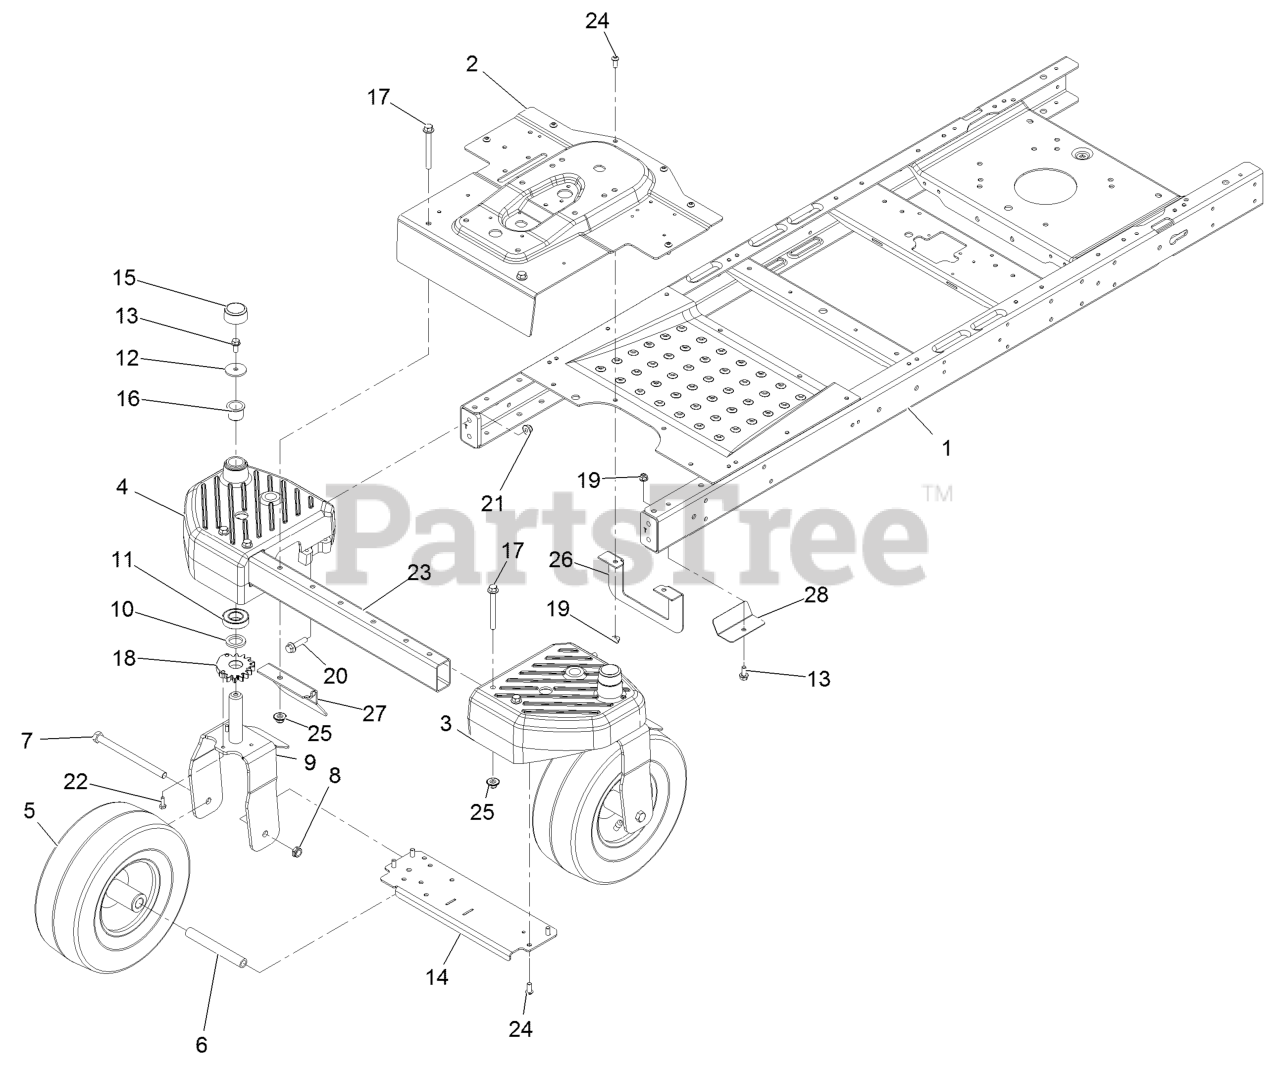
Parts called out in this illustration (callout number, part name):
1	FRAME ASM
2	PAN-STEER, FRONT
3	HOUSING-SPINDLE, LH
4	HOUSING-SPINDLE, RH
5	13 INCH WHEEL AND TIRE AS
6	SPANNER
7	WASHER-LOCK
8	NUT-HEX
9	CASTER FORK ASM
10	WASHER-THRUST
11	BEARING-BALL
12	WASHER-FLAT
13	SCREW-HHF
14	PLATE-BRIDGE, NARROW
15	CAP-CASTER
16	BUSHING-PIVOT
17	SCREW-HHF
18	GEAR-WHEEL, 15 TOOTH
19	NUT-HF, NI
20	SCREW-HHF
21	NUT-HF, NI
22	SCREW-HH
23	TUBE-FRONT, NARROW
24	SCREW-HSBH
25	Nut-Nyloc 3/8-16 Flg
26	BRACKET-UPSTOP, LONG
27	GUARD-FRONT
28	PLATE-GUARD
